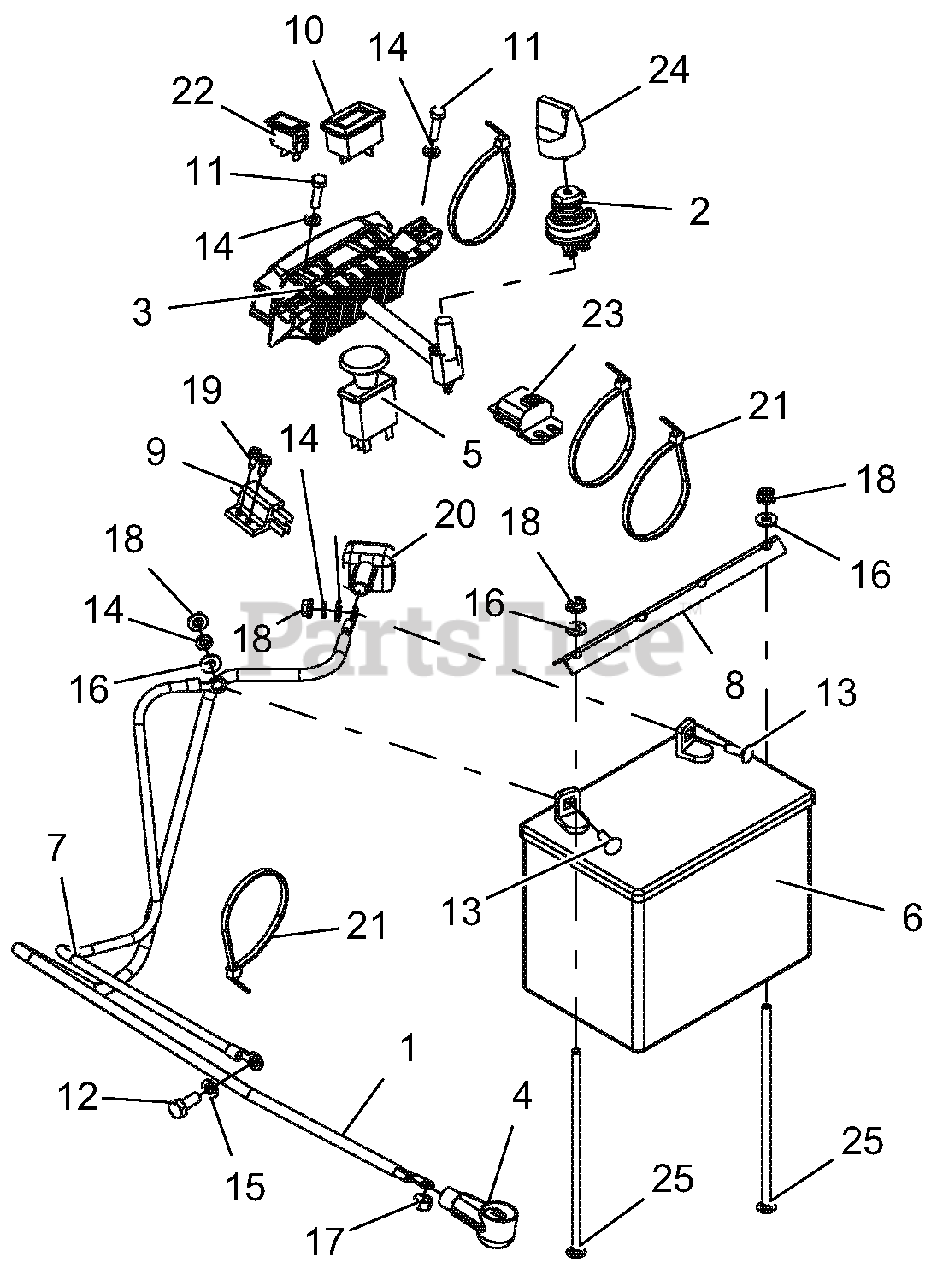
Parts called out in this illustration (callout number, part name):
1	CABLE, BATTERY - 42" POSITIVE
2	SWITCH, IGNITION
3	HARNESS, PROSTANCE WIRING
4	BOOT, BATTERY TERMINAL-RED
5	SWITCH, CLUTCH
6	BATTERY, 300 CCA 10U1L
7	CABLE, NEGATIVE BATTERY 35.00"
8	HOLD DOWN - BLK
9	SWITCH- DOUBLE POLE N.O./N.O.
10	METER, HOUR W/MAINTENANCE
11	@BLT-HEX M6-1.0X25 YWZC
12	@BLT-HEX M8-1.25X20 YWZC
13	BLT-RDHDSQNK .25-20X.75 G5 YWZC
14	WSHR-LK .25X.062 REG YWZC
15	WSHR-LK .31X.078 REG YWZC
16	WSHR-FL-STL.281X.62X.065 YWZC
17	NUT-LK-TOP M8-1.25 YWZC
18	@NUT-SPNLK-FLG .25-20 YWZC
19	SCR-TAP 10-24X.50 HWH TR YWZC
20	INSULATOR
21	CABLE, TIE 5.50 LG
22	LIGHT, INDICATOR
23	MODULE, INTERLOCK
24	KEY, W/ COVER
25	BLT-RDHDSQNK .25-20X7.50 G2 YWZC
